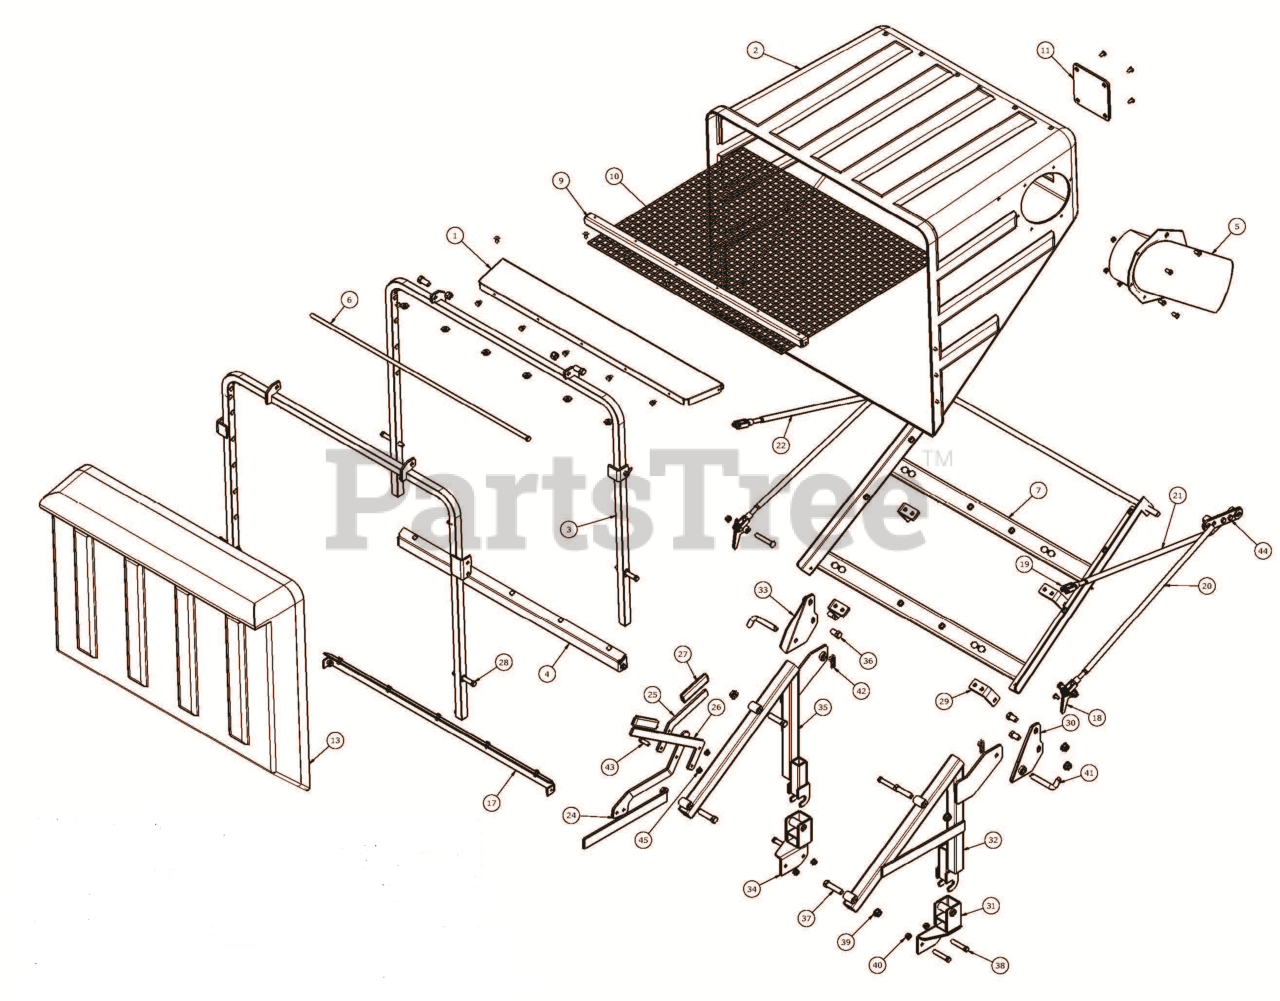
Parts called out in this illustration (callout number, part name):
1	ASM, PV18 DFS HOUSING
2	HOUSING, PV18 DFS COMPOSITE
3	FRAME DFS CATHER HOUSING
4	FRAME, DFS CATHER HOUSING BTM
5	TUBE, CATCHER INTAKE
6	ROD , SUPPORT SCREEN
7	ASM, DUMP CATHER BASE PIVOT
8	ASSY, SCREEN
9	SUPPORT, SCREEN
11	WINDOW VIEWING
12	DOOR, CATCHER
13	CATCHER DOOR, PLASTIC
14	ASSEMBLY, CATCHER DOOR
16	VENT, DOOR SPACER
17	FRAME, CATCHER BOTTOM
18	LATCH, HOUSING
19	END, 3/8 YOKE
20	LATCH ROD
21	ROD, HINGE RIGHT
22	ROD, HINGE LEFT
23	ASM, CATCHER HANDLE
24	HANDLE , DUMP BASE
25	HANDLE, DUMP FRONT
26	HANDLE, DUMP REAR
27	GRIP, HANDLE
28	BOLT, SPACED LATCH
29	BRKT, BASE FRAME
30	PLATE, RIGHT ROPS
31	WLDMT, RIGHT FRAME MOUNT BRKT
32	WLDMT, RIGHT FRAME BRACKET
33	PLATE, LEFT ROPS
34	WLDMT, LEFT FRAME MOUNT BRKT
35	WLDMT, LEFT FRAME MOUNT BRKT
36	BLT, HEX .50-13X1.00 G5 ZCC
37	BLT, HEX .50-13X2.50 G5 ZCC
38	BLT, HEX .38-16X2.50 G5 ZCC
39	NUT-LK-CTR-FLG .500-13 GG ZCC
40	NUT-LK-CTR-FLG .375-16 GF ZCC
41	BENT PIN 1/2" X 3"
42	PIN-HAIR-EXT .12X.31X2.37 YWZC
43	BLT, HEX .31-18X1.25 G5 ZCC
44	BLT,HEX .38-16X1.00 G5 ZCC
45	NUT,LK-CTR-FLG .31-18 GF ZCC
